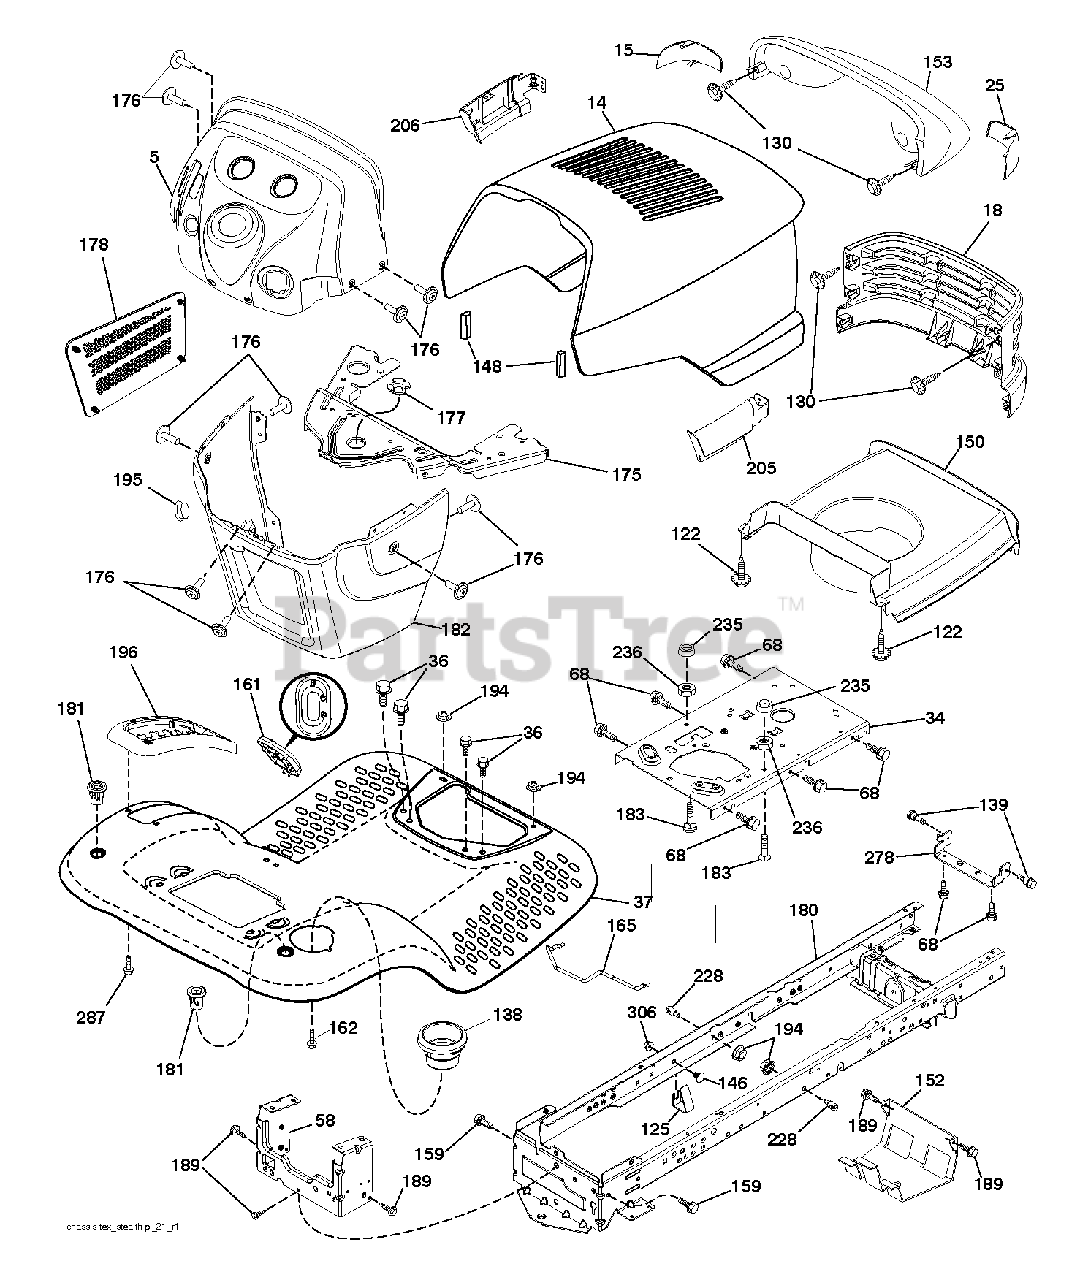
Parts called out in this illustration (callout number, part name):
5	DASH.UPR.STEALTH.BLACK
14	HOOD.ASM.DIXON.STEATH.SRS.BLUE
15	LENS LH
18	GRILLE.STEALTH.GT.BLACK
25	LENS RH
34	PLATE.ENGINE.WELDED.CHASSIS
36	SCREW 5/16"
37	FENDER.TLT.W/CPH.W/FW.666
58	DRAWBAR UPPER 2PC SMALL FENDER
68	SCREW LT
122	SCREW.WSHD.HEX10-32X5/8
125	CLIP.FUEL.LINE
130	SCREW.#10 X 0.750.BOS (2 2)
138	CUPHOLDER.TL.TEX.BLACK
139	BOLT, SHOULDER 5/16-18
146	BOLT.RDHD.SHT.SQNK.3/8-16X5/8
148	EXTRUSION BUMPER
150	DUCT.HEAT.HOOD.STEALTH.GT
152	SHIELD.BROWNING.W/TEX
153	LIGHTBOX.ASM.STEALTH.DL.DIXON
159	SCREW, 3/8-16X3/4
161	WINDOW.FUEL.LT.TEX.BLACK
162	SCREW.HI-LO.CONSOLE
165	SUPPORT.TANK.REAR.W/TEX
175	CROSSMEMBER.
176	SCREW.#10-24X5/8.RN.QU
177	BUSHING,STEERING
178	CARGO.ASM.NET.DASH.LOWER
180	CHASS.WLDMNT.TL.12GA/2P.48/54
181	FEND/FTRST.PCH.CPH.NFW
182	DASH.LOWER.
183	BOLT.5/16-18X1-1/4 FULL THD
189	SCREW
194	NUT LOCK HEX FLANGE 5/16-18
196	CONSOLE.ASM.DECKLFT.BL/RBT.TLT
205	SKIRT.GRILLE.STEALTH.RH
206	SKIRT.GRILLE.STEALTH.LH
228	STUD.FASTNER.W/ANTI-ROTATE
235	SPACER FENDER
236	NUT.CENTERLOCK.5/16-
278	BRKT.HOOD/MUFF.STEALTH
287	SCREW 1/4X20
306	NUT LOCK FLG 3/8-16 UNC
